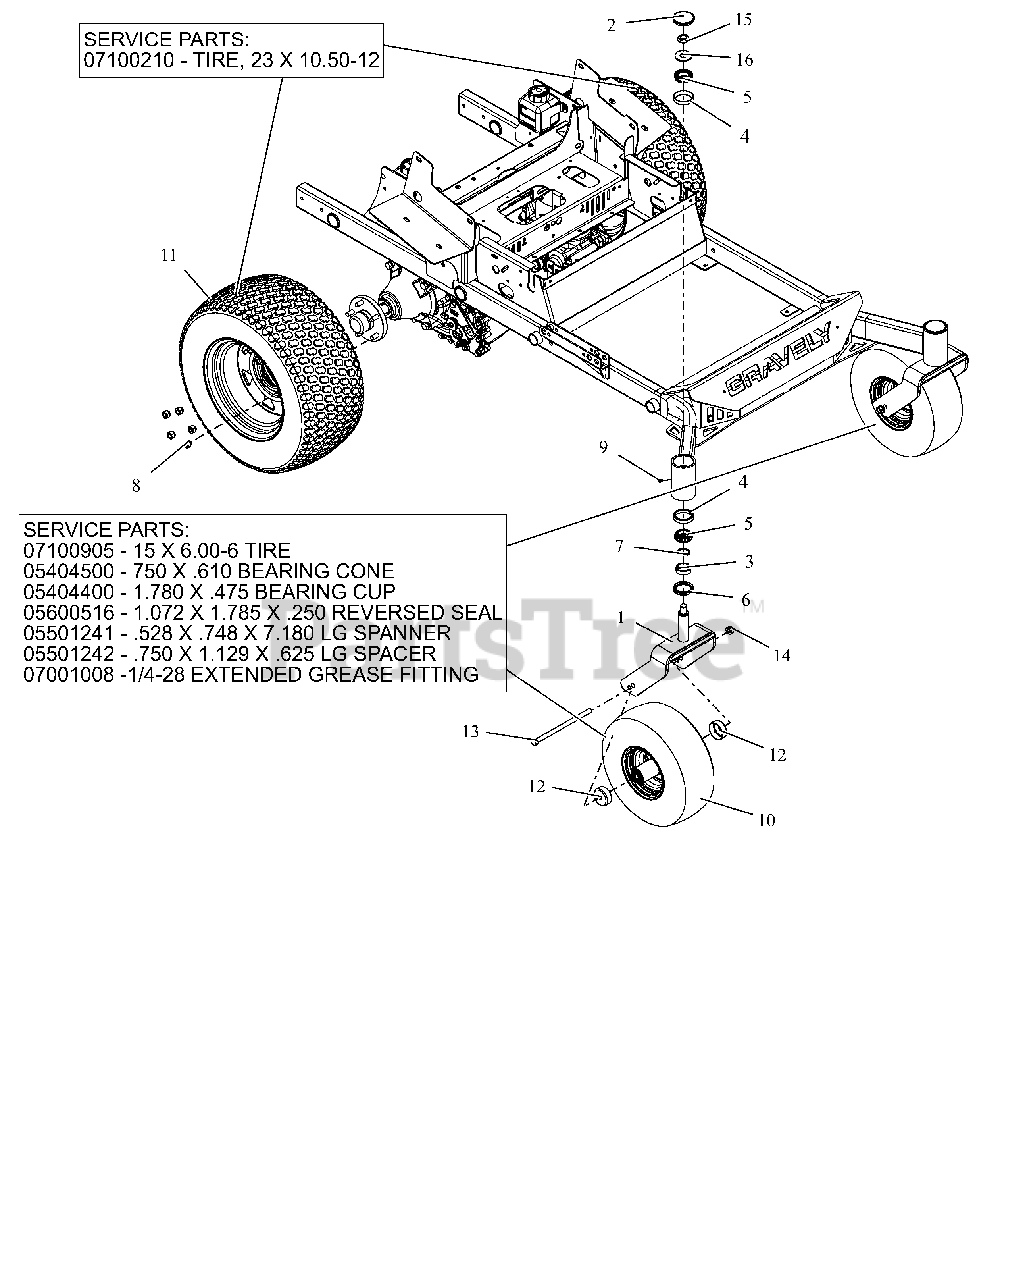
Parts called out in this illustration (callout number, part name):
1	CASTER FORK WMT - RED
2	CAP, DUST
3	SPCR, FRONT CASTER FORK
4	BRG-CUP 2.328X.465
5	BRG-CONE 1.25X.66
6	SEAL, OIL 1.75 X 2.332 X .312
8	NUT, WHEEL .50-20 ZCC
9	FTG, .25-28 FLUSH MNT GREASE
10	ASM, WHL/TIRE 15X6.00-6 SMOOTH
10	TIRE, 15X6-6 SMOOTH
10	BRG-CONE .750X.61
10	BRG-CUP 1.781X.475
10	SEAL,1.072X1.785X.250 REVERSED
10	SPANNER, .528X.748X7.18 LG
10	SPACER, .750X1.129X.625 LG
10	GREASE FITTING 1/4-28 EXTENDED
11	ASM, WHL/TIRE 23X10.50-12 K500
11	TIRE, 23X10.00-12
12	SHIELD, WHEEL BEARING
13	BLT, HEX .50-13X9.00 G5 ZCC
14	NUT-LK-TOP-FLG .500-13 GF ZCC
15	NUT, JAM-TOPLOCK .750-16 ZCC
16	WSHR-FL-STL 0.812X2X0.148 ZCC
